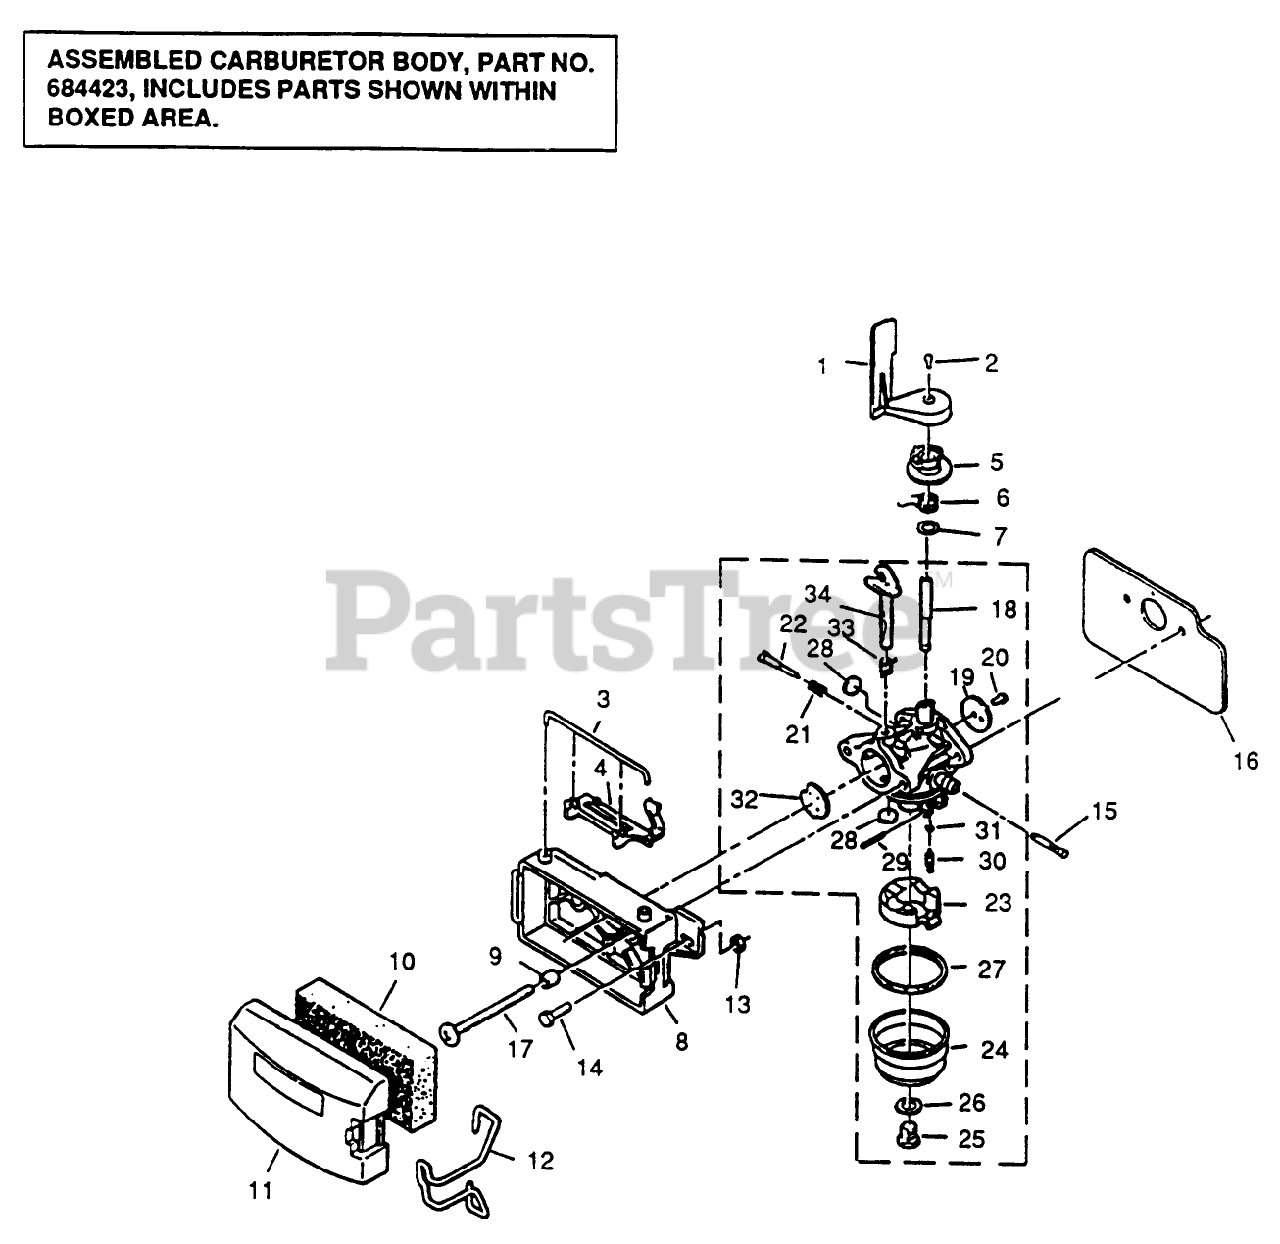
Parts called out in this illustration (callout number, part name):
1	AIR VANE F
2	SCREW F
3	RETAINER
5	COLLAR A/VAVE F
6	THROTTLE SPR E
7	WASHER VF
9	SPACER
12	RETAINER-COVER, FILTER
14	SCREW
15	SCREEN FUEL PITTS
16	Heat Shield
17	SCREW
18	Throttle Shaft
19	Throttle Valve
20	Screw-Throttle Valve
21	Spring-Idle Needle
22	Idle Needle
24	Fuel Bowl
25	Screw-Bowl Retainer
26	Bowl Retainer Gasket
27	Fuel Bowl Gasket
28	Plug-Welch
29	Float Shaft
30	Inlet Needle Valve
31	Valve Seat
32	Choke Valve
33	Choke Return Spring
34	Choke Shaft
